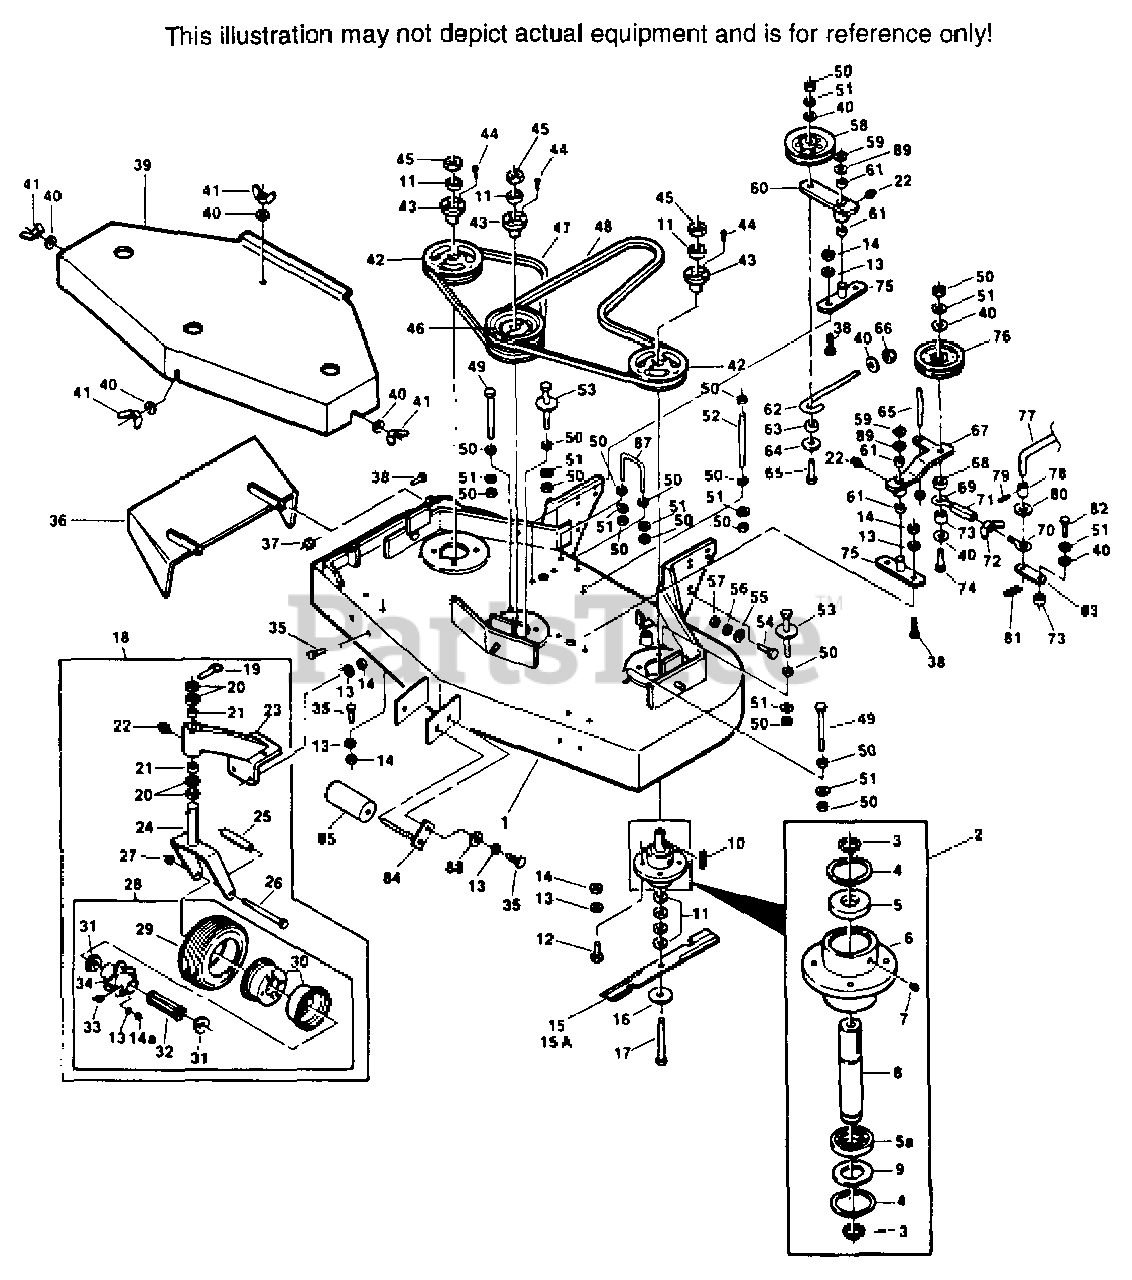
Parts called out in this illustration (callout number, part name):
2	CUTTER SPINDLE ASSY.(INCL. 3-9)
3	RETAINING RING, 1" EXT.-INVERTED
4	RETAINING RING, 2-7/16" INT.BASIC
5	BEARING, CUTTER SPINDLE UPPER
5A	BEARING, CUTTER SPINDLE LOWER
6	SPINDLE HOUSING
7	GREASE FITTING STR. 5/16 SERR.
8	SPINDLE, CUTTER BLADE
9	WASHER, 1-5-16 X 2-13/32 X 16 GA
10	KEY, 1/4 X 1/4 X 2
11	SPACER, CUTTER BLADE
16	FLAT WASHER, 5/8"W
17	HEX HD BOLT, 5/8-11 X 9-1/2"
18	CASTER ASSY, COMP.(INCL. 19-28)
19	QUICK PIN
20	SPACER, CASTER YOKE, 1/2" LONG
21	BRONZE BEARING
22	GREASE FITTING, STR., 1/4-28
23	SUPPORT ASSY.(INCL. 21-22)
24	CASTER YOKE WLD.
25	SLEEVE, CASTER WHEEL BEARING
26	HEX HD BOLT, 1/2-13 X 5-1/2"
28	WHEEL ASSY.(INCL. 13-14A, 29-34)
29	TIRE ONLY, CASTER WHEEL
29	INNER TUBE ONLY, CASTER WHEEL
30	RIM PAIR, CASTER WHEEL
31	RETAINER, BEARING, CASTER WHEEL
32	ROLLER BEARING, CASTER WHEEL
33	GREASE FITTING 45' 1/4-28
34	HUB ASSY, CASTER WHEEL
37	HEX NUT, 5/16-18 ELASTIC STOP
40	WASHER 25/64 X 15/16 X 12 GA.
41	WING NUT, 3/8-16
42	PULLEY(INCL. 43-44)
43	TAPERED HUB
46	PULLEY, DOUBLE(INCL. 43-44)
50A	HEX NUT 3/8-16, CENTERLOCK
52	SUPPORT, BELT COVER
53	BELT GUIDE WLD.
55	WASHER, 15/32 X 59/64 X 16 GA.
58	IDLER PULLEY, "V" GROOVE
59	RETAINING RING, 3/4" EXT."E"
60	IDLER ARM ASSY,(INCL. 22 & 66)
61	BRONZE BEARING
62	ROD, IDLER PULL, J
63	SPACER, J PULL ROD
64	WASHER, 3/8 X 1-1/2 X 16 GA.
66	HEX NUT, 3/8-16 ELASTIC STOP
67	IDLER ARM(INCL. 22 & 61)
68	SPACER
69	EYEBOLT, LH
70	EYEBOLT, RH
71	TURNBUCKLE
72	WING NUT, 5/16-18
73	SLEEVE, CAM CLUTCH
75	IDLER PIVOT WLD.
76	IDLER PULLEY, BELT CLUTCH
77	BLADE CLUTCH ROD, LOWER
78	SLEEVE, CLUTCH ROD
80	WASHER, 33/64 X 1 X 16 GA
81	HAIR PIN LARGE
83	CAM LINK
87	BELT GUIDE
